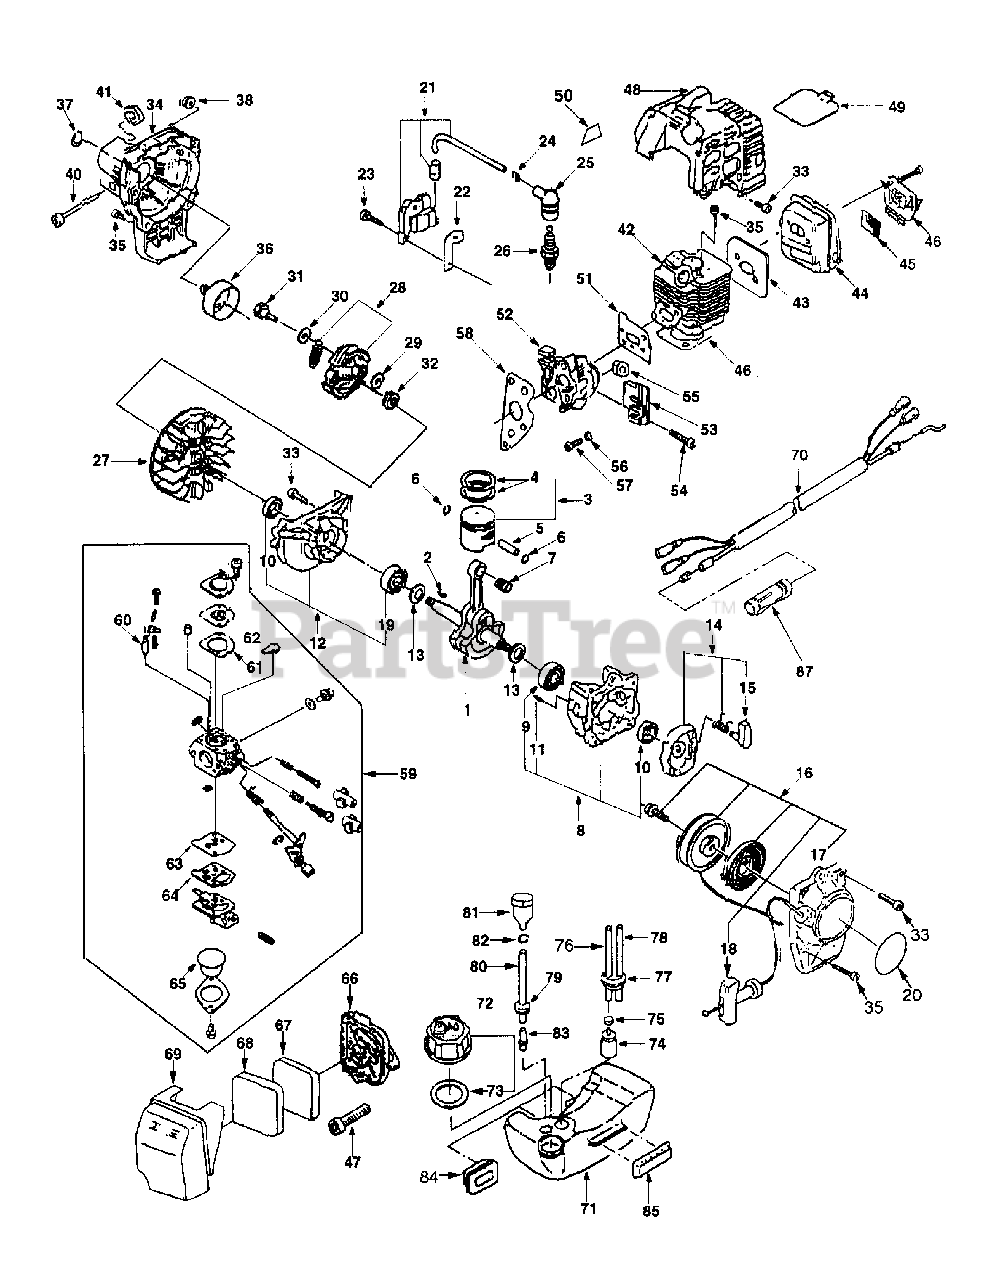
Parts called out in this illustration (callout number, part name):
1	Crankshaft
3	Piston Ass'y
4	Ring, Piston
5	Pin, Piston
6	Clip, Piston Pin
7	Needle Bearing
8	Crankcase Ass'y
9	Ball Bearing; 6000
10	Oil Seal
11	Dowel Pin
12	Crankcase Ass'y
13	Shim; 0.1
13	Shim; 0.2
14	Pulley Ass'y, Starter
16	Recoil Ass'y
17	Rope, Starter
18	Knob, Starter
19	Ball Bearing; 6200
20	Name Plate
21	Coil Ass'y, Ignition
22	Insulator
23	Bolt; M4 X 20
25	Cap, Plug
26	Spark, Plug
27	Flywheel, Magneto
28	Clutch Ass'y
33	Bolt; M5 X 20
34	Housing, Blower
35	Bolt; M5 X 16
36	Drum, Clutch
37	Snap Ring; S-10
40	Bolt; M5 X 30
42	Cylinder
43	Gasket, Muffler
45	Arrester
47	Bolt; M5 X 48
48	Cowling, Cylinder
49	Baffle Plate
50	Trade Mark
51	Gasket, Insulator
52	Insulator
53	Adjuster
54	Bolt; M5 X 12
56	Washer
57	Bolt; M5 X 25
58	Gasket, Carburetor
59	Carburetor Ass'y
60	Valve, Float
62	Diaphragm, Metering
63	Diaphragm, Pump
66	Case, Air Silencer
67	Element(B), Filter Air
68	Element(A), Filter Air
69	Case, Cap
70	Wire Compl, Throttle
71	Tank, Fuel
72	Cap Ass'y, Fuel Tank
74	Filter, Fuel
78	Hose
81	Valve Assy, Reversing
83	Connector
85	Rubber
86	Gasket Kit
87	Wire Holder
89	Spring, Spiral
91	Spring, Return
